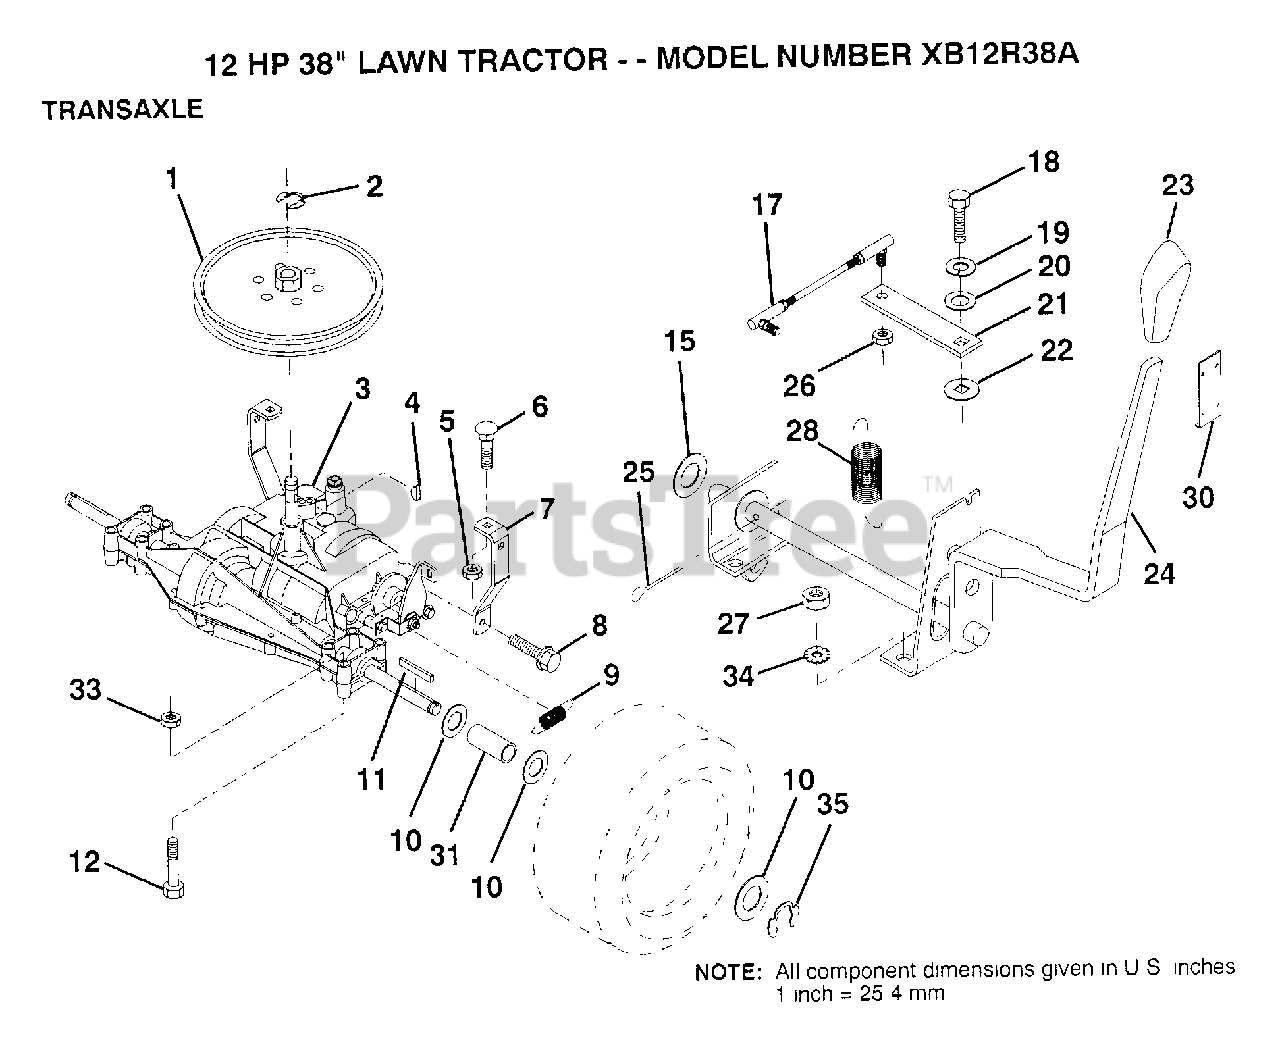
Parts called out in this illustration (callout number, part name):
1	PULLEY
6	BOLT
7	"STRAP,TORQUE"
8	SCREW
10	WASHER
11	SQUARE KEY
12	BOLT
17	"LINK,SHIFT"
19	LOCKWASHER
20	WASHER LT
21	"ARM,SHIFT"
22	WASH-SHFT PLT LT
23	"KNOB,SHT CONTROL"
25	PIN COTTER 1/8
26	NUT.LOCK.5/16-24
28	"SPRING,EXT"
30	KNOB RETAINER
31	SPACER
34	LOCKWASHER.5/16.E
35	E-RING LT
